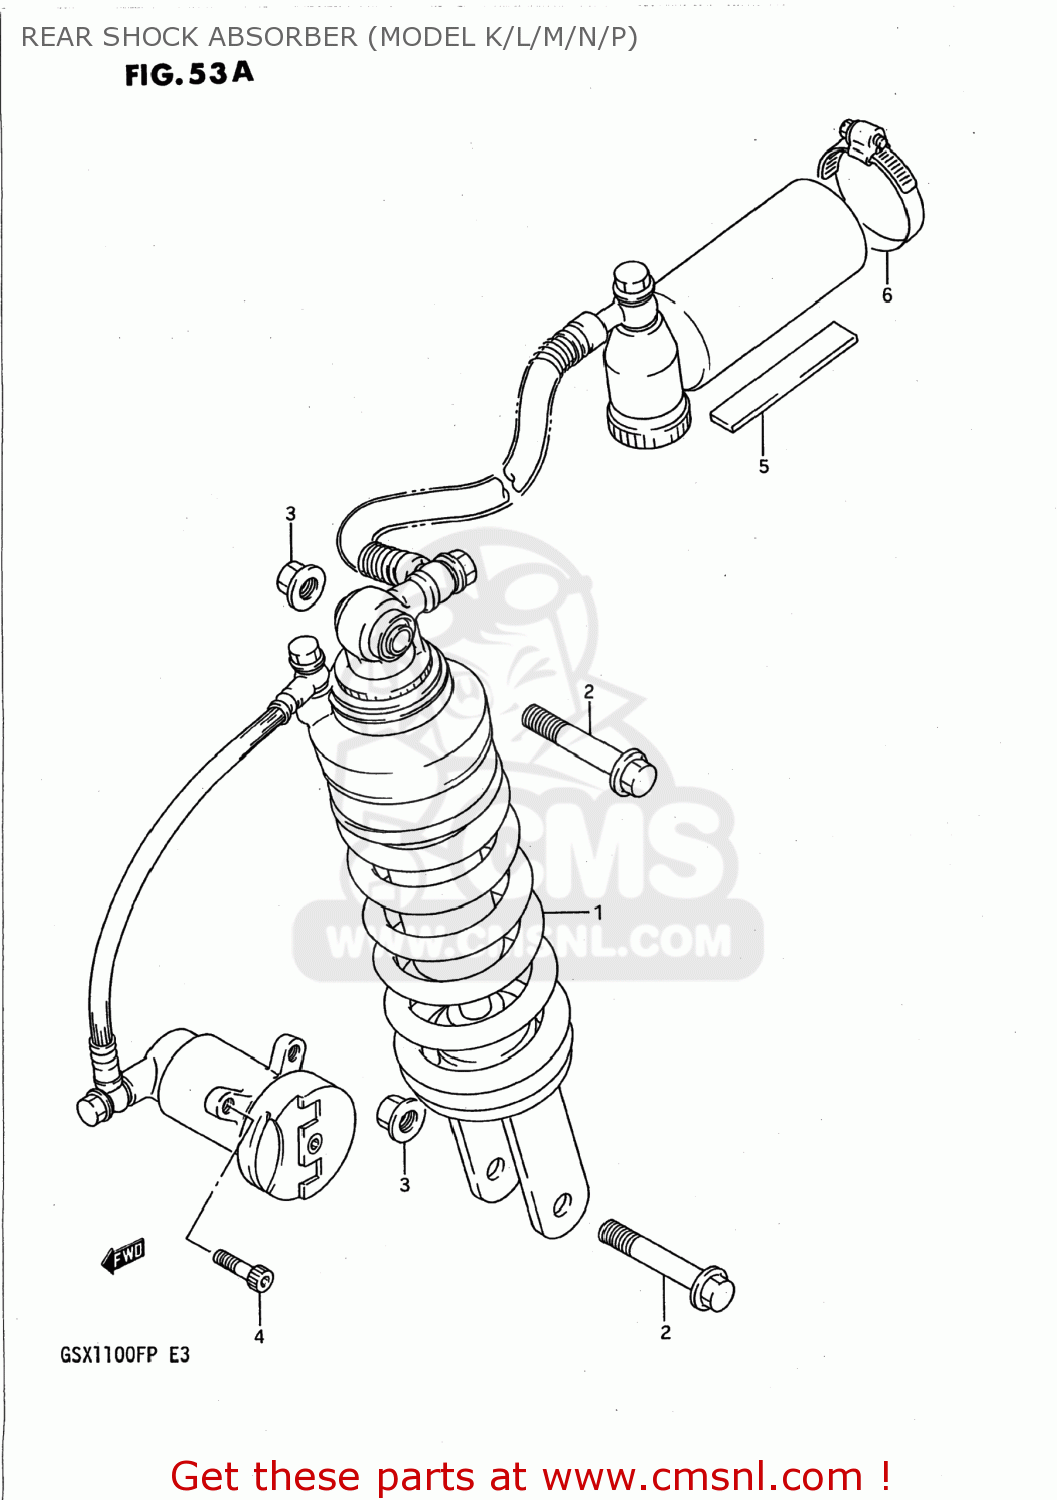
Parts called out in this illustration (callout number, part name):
1	ABSORBER ASSEMBLY,REAR SHOCK
2	BOLT(10X54)
3	NUT
4	BOLT
5	CUSHION, RESERVOIR TANK
6	CLAMP
